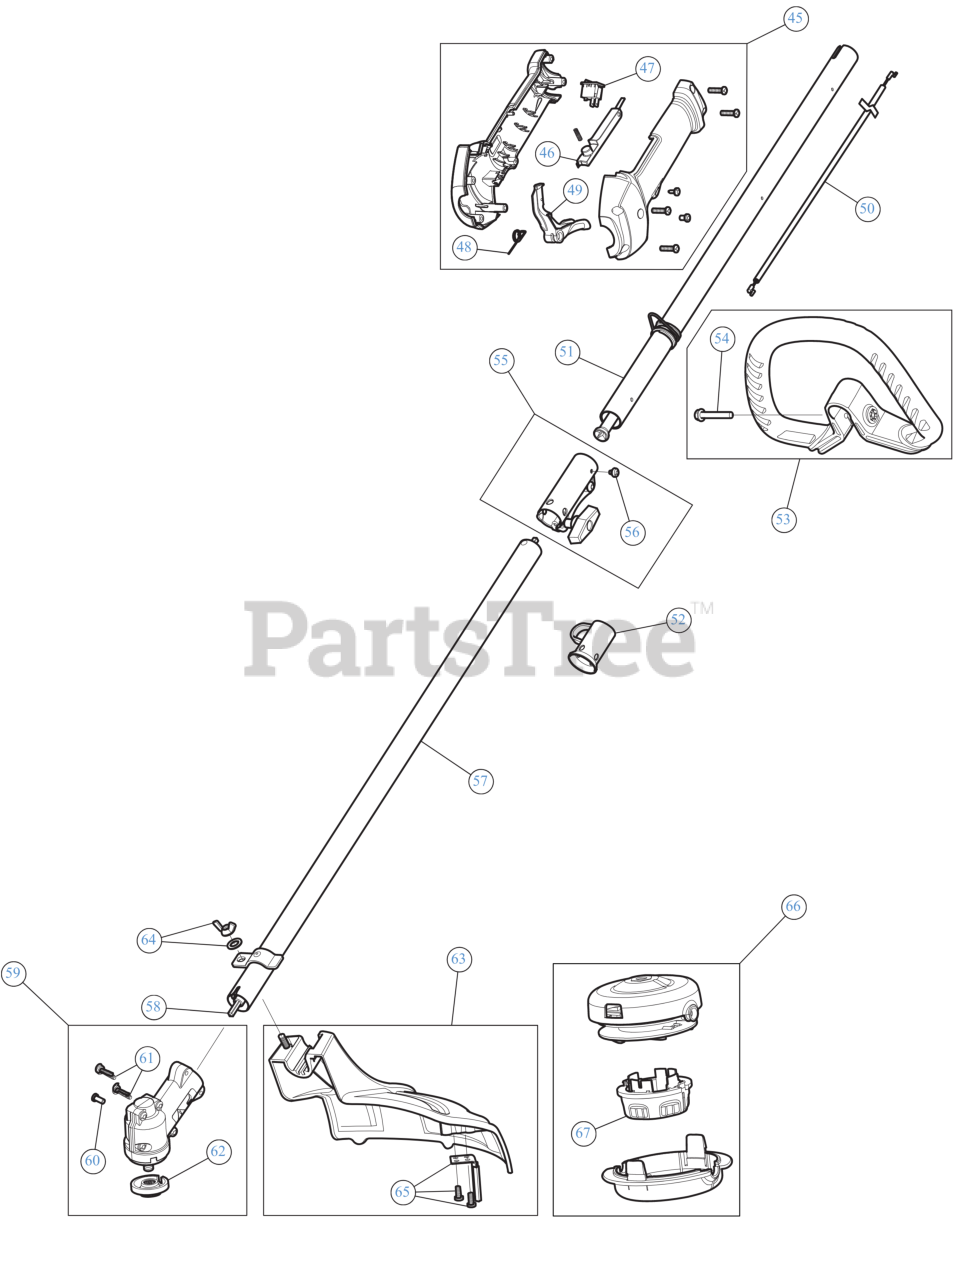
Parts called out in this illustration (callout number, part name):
45	THROTTLE GRIP ASSEMBLY
46	LEVER LOCK OUT
47	SW, MOMENTARY ON/O
48	SPRING TRIG
49	THROTTLE TRIGGER
50	THROTTLE CABLE
51	BOOM ASSEMBLY UPR
53	HANDLE ASSEMBLY
54	BOLT 1/4-20X1 1/2
55	SPLIT BOOM COUPLER KIT
56	SCREW, 10-32X.250 TA
57	BOOM ASSEMBLY LOWER
58	LOWER DRIVE SHAFT
59	GEARBOX LCBC
60	SCREW, 8-32 x .312 P
62	CUTTING HEAD SPACER
63	GUARD/BLADE ASM
64	BLADE GUARD MOUNTING HARDWARE
65	BLADE ASSEMBLY W/HDW
66	CUTTING HEAD
67	BUMPKNOB CNT LRG
